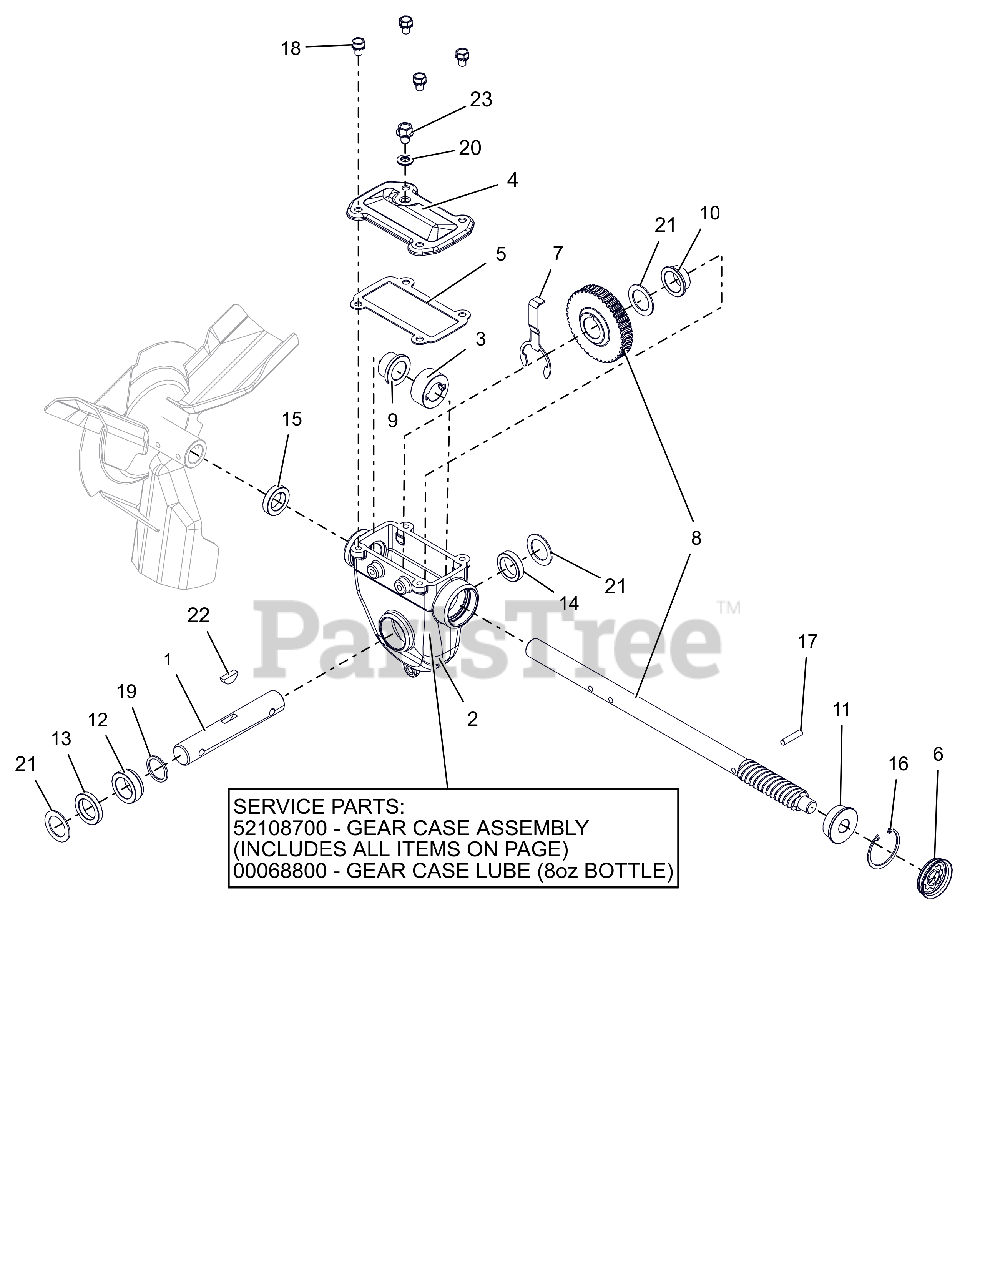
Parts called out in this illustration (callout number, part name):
1	RAKE SHAFT, SHORT-COMMON
2	GEARCASE, LARGE MACHINED
2	KIT, SERVICE - DLX GEAR CASE
2	ARIENS L3 LUBE, 8 OZ BOTTLE
3	THRUST COLLAR, .875"ID SLIPFIT
4	COVER, TOP - LARGE IRON
5	GASKET, TOP - LARGE GEARCASE
6	COVER, GEAR CASE 1.75"
7	BUSHING RETAINER, LARGE
8	KIT, SERVICE-WORM SHAFT & GEAR
9	BSHG-FLG .879X1.128X.75X1.45
10	BSHG-FLG 1.006X1.128X.555X1.45
11	BSHG-FLG .628X1.503X.58X1.725
12	BSHG-FLG LARGE, RIGHT
13	SEAL-OIL .999X1.500X.250 TBC29
14	SEAL-OIL .999X1.375X.312 TBC29
15	SEAL-OIL .873X1.375X.312 TBC29
16	RG-RTNG-INT 1.750X.062
17	PIN-STR .250X1.12 6150
18	BOLT, SEMS .31-18X.50 GR5 YWZC
19	WSHR-FL-STL 1.010X1.250X.068YZ
20	WSHR-BND-SEAL .38X.75X.11 GALV
21	WSHR-FL-STL 1.010X1.505X.062YZ
22	KEY-WDRF .25X.875 HRD #A
23	@SCR-ROLOK .38-16X.50 HWH YWZC
